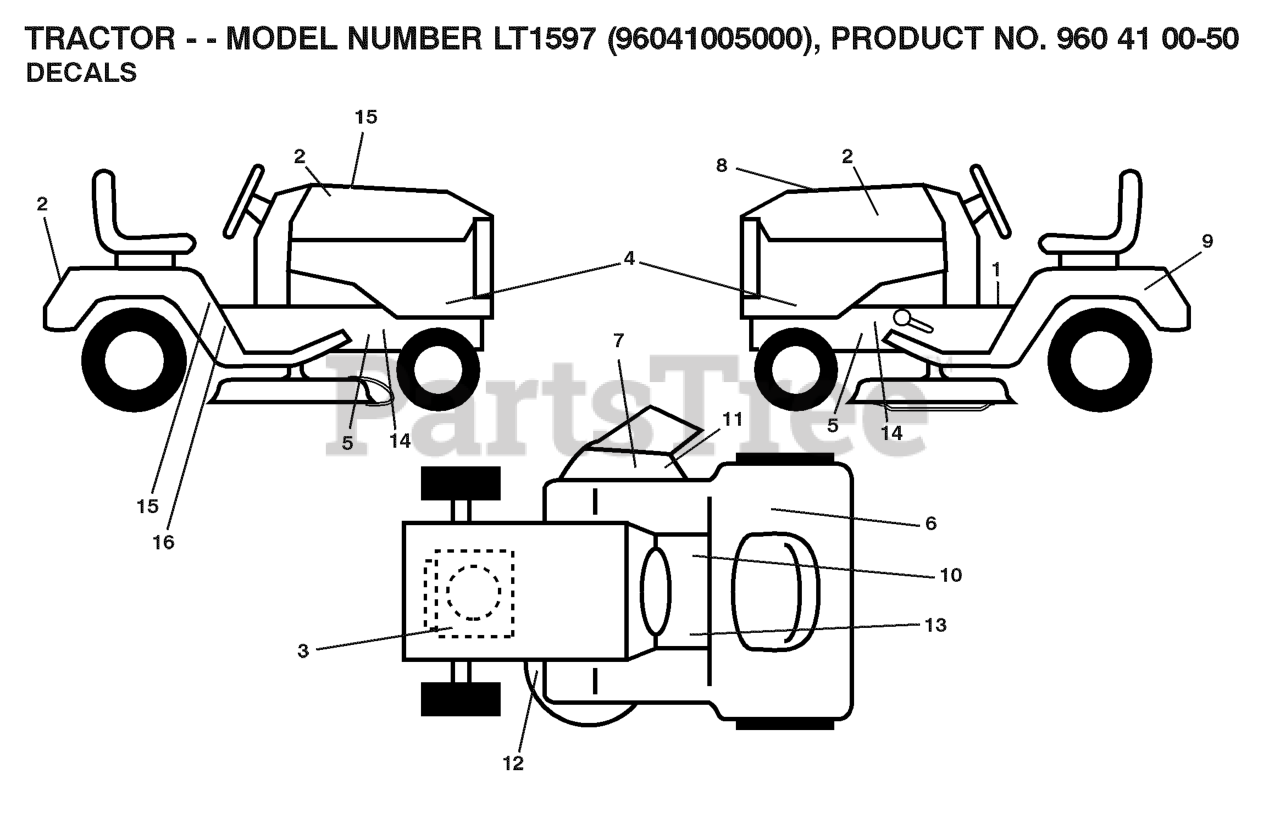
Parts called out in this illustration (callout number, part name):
1	LABEL
2	DECAL.HOOD.NAMELOGO.HUSQ
3	DECAL
6	Decal, Fender 100 DB/CE
7	DECAL.INTERNATIONL.CUTFINGER
8	DECAL.WHEEL.STRG.LGN.H
9	DECAL BTRY SYMBOLS
10	DECAL PARK BRAKE
11	DECAL, DEFLECT WARNING
12	DECAL.V-BELT.SCHEMATIC.36/38/9
13	DECAL
15	DECAL 80 DBA
16	DECAL
